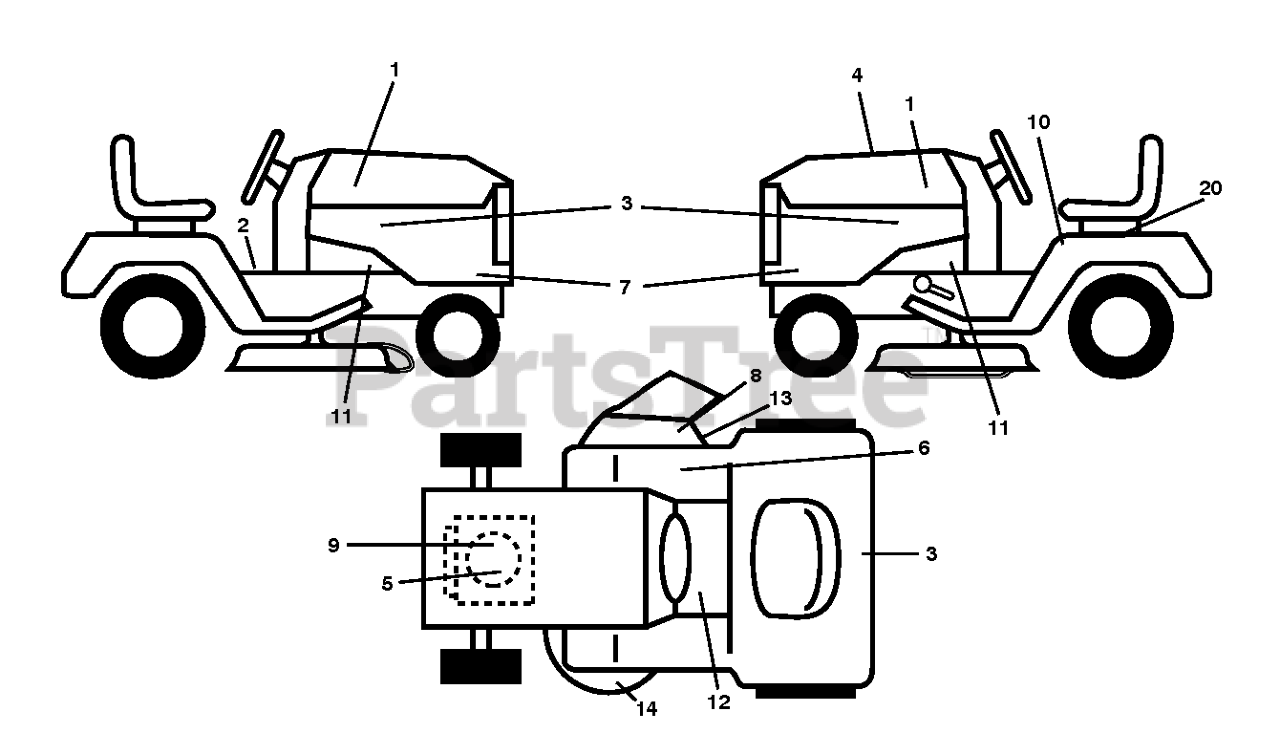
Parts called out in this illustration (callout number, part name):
2	DECAL PARK BRAKE
3	DECAL.HOOD.LOGO.ORANGE.HUSQVAR
5	DECAL
6	Decal, Fender 100 DB/CE
8	DECAL.INTERNATIONL.CUTFINGER
10	LABEL
12	DECAL
13	DECAL, DEFLECT WARNING
14	DECAL.V-BELT.SCHEMATIC.36/38/9
20	DECAL BTRY SYMBOLS
